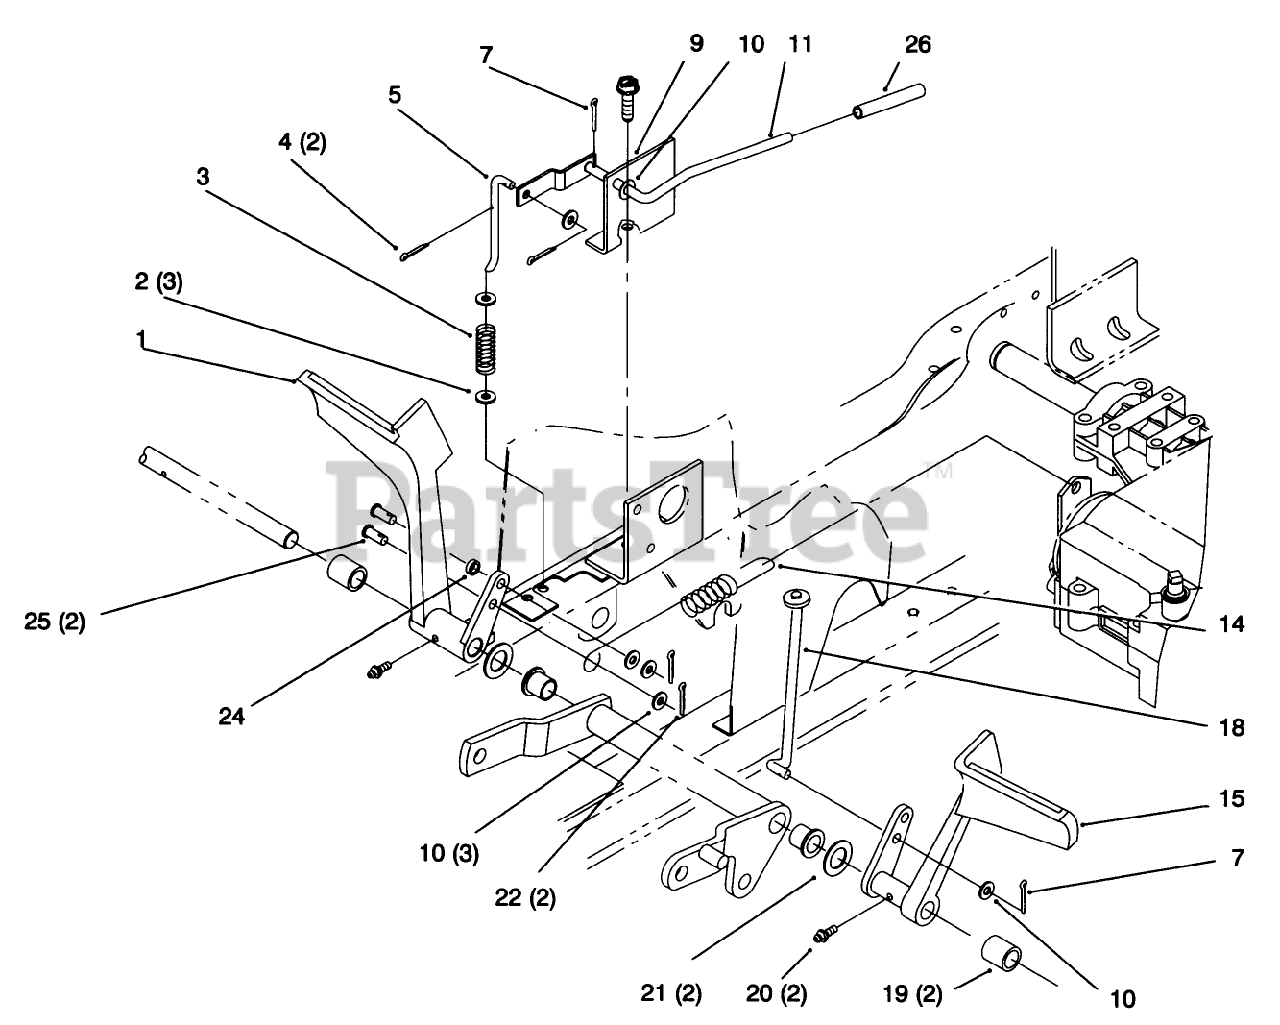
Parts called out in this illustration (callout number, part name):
2	WASHER-FLAT
4	PIN-COTTER
5	ROD - PARKING BRAKE
7	PIN-COTTER
10	WASHER-PLAIN
11	PARK BRAKE LVR WA*B
15	PEDAL-CLUTCH
18	CLUTCH ROD WA
19	SPACER
20	FITTING-GREASE
21	WASHER-WAVE
22	PIN-COTTER
24	BUSHING
25	PIN-CLEVIS
26	GRIP - PARKING BRAKE
